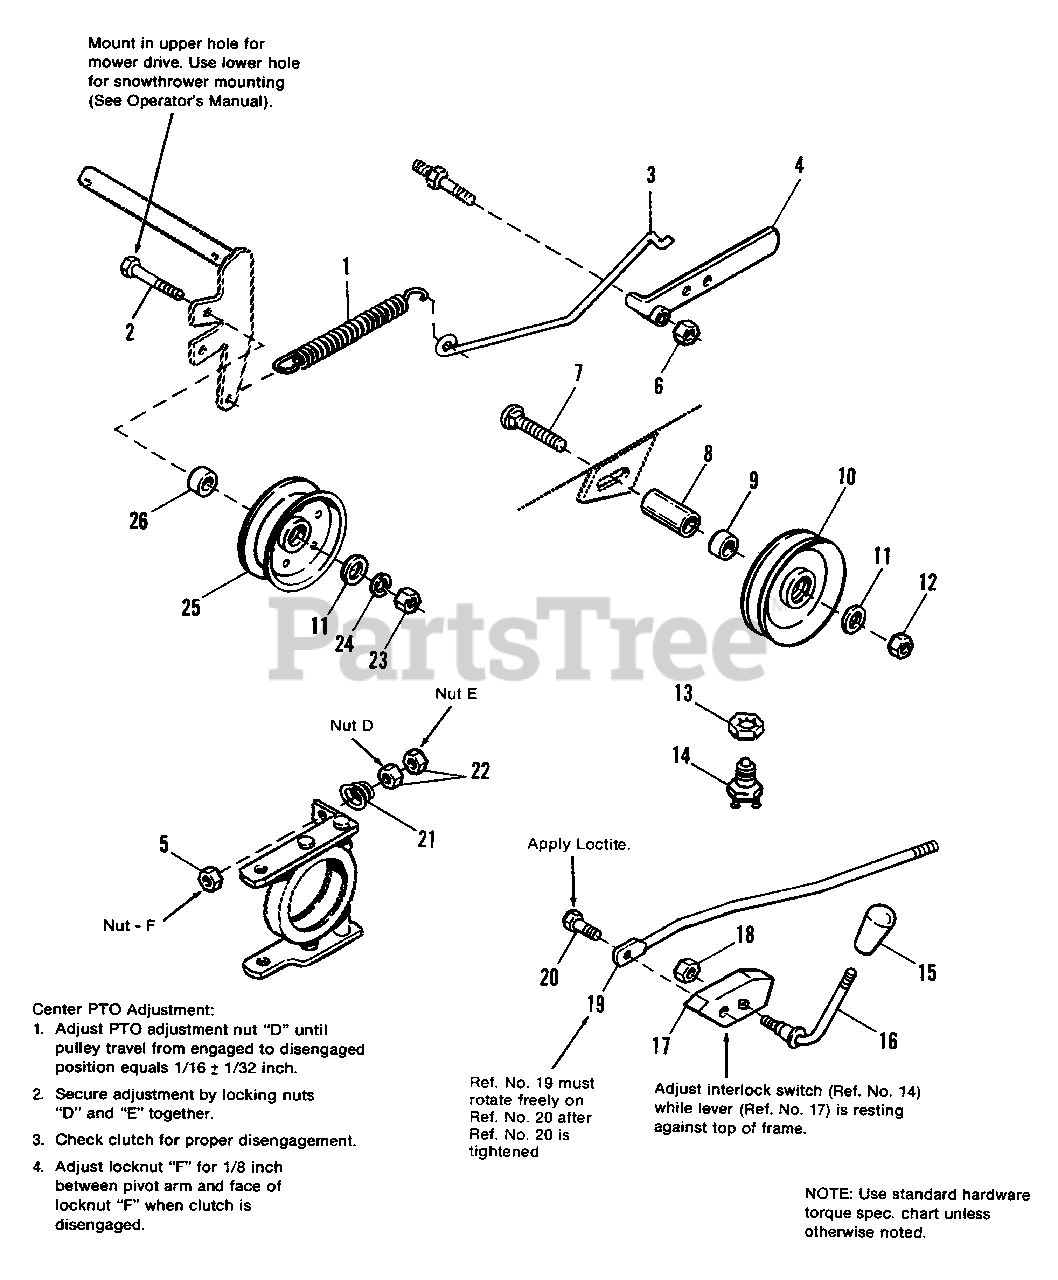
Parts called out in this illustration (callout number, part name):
1	SPRING, Tension
2	CAPSCREW, Hex Hd., 3/8-16 x 2
3	ROD, Tension
4	HANDLE ASSY.
5	LOCKNUT, Hex, Jam, Cntr. 5/16-18
6	LOCKNUT, Hex, 7/16-14
7	BOLT, Carriage, 3/8-16 x 1-3/4
10	PULLEY ASSY., w/Bearings
11	WASHER, Plain, 3/8
12	LOCKNUT, Whizlock, Flange, 3/8-16
13	NUT, Pal
14	SWITCH, Interlock
15	KNOB
16	HANDLE, PTO, Clutch
18	LOCKNUT, Hex, 3/8-16
19	ROD ASSY., Control
20	CAPSCREW, Special
22	NUT, Hex, Full, 5/16-18
23	NUT, Hex, Full, 3/8-16
24	LOCKWASHER, 3/8
25	PULLEY, Idler
